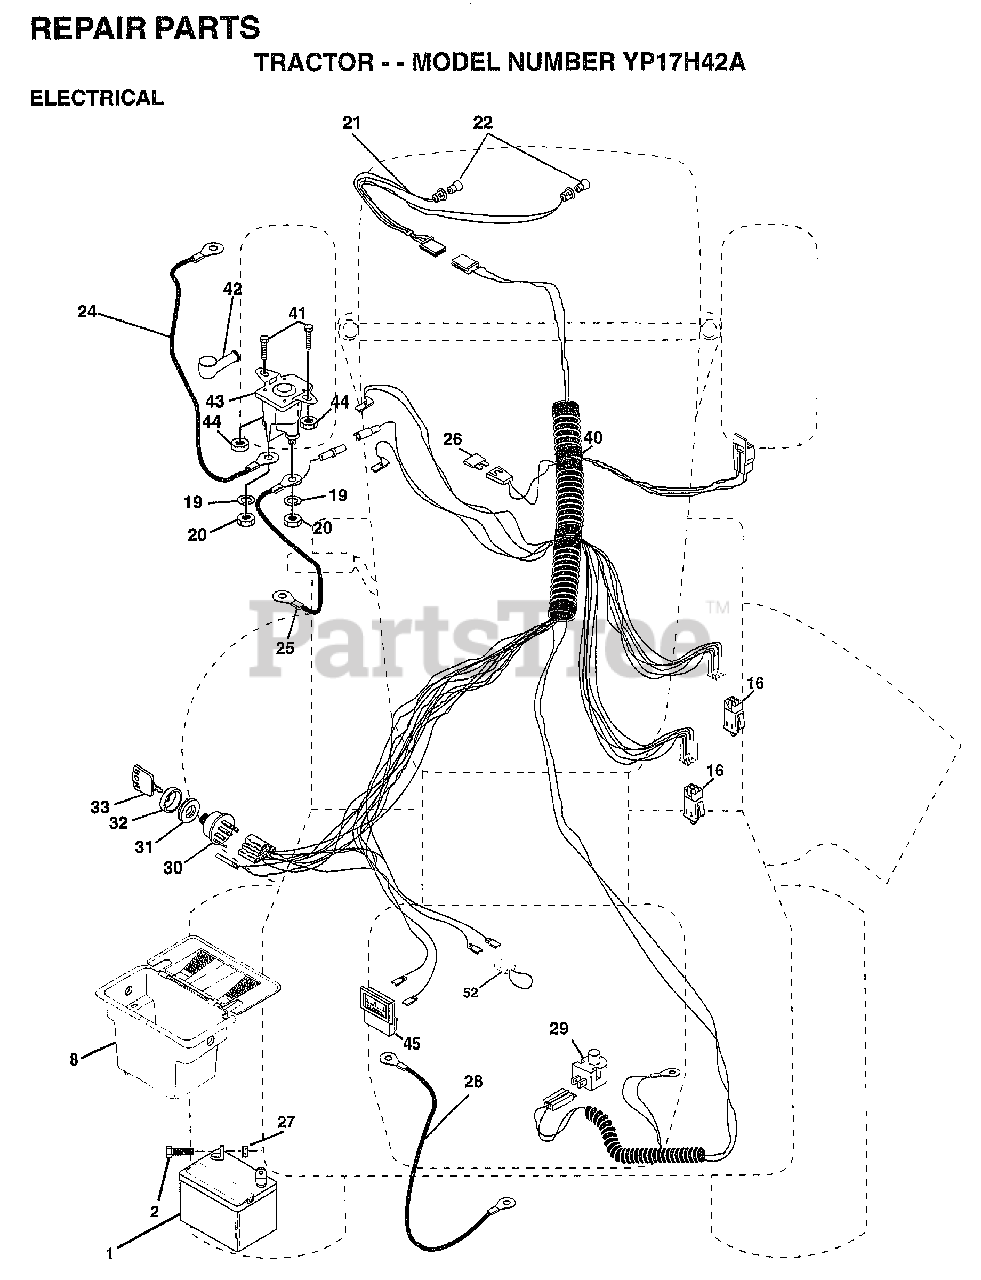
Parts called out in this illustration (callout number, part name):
2	BOLT LT
8	"CASE,BATTERY.MECH"
16	SWITCH INTERLOCK
20	NUT
21	HARNESS.ASM.LIGHT W/4152J
22	HEADLAMP BULB
24	CABLE ASM.
25	CABLE.BTRY.6GA.RD
26	FUSE.15 AMP
27	NUT
29	SWITCH SEAT
30	SWITCH IGN 4POS
31	NUT IGNITION
32	COVER KEY SWITCH
33	KEY
40	HARNESS.IGNITION
41	BOLT HXHD FIN
44	NUT HXKEP 1/4X20
52	PROTECTION LOOP
